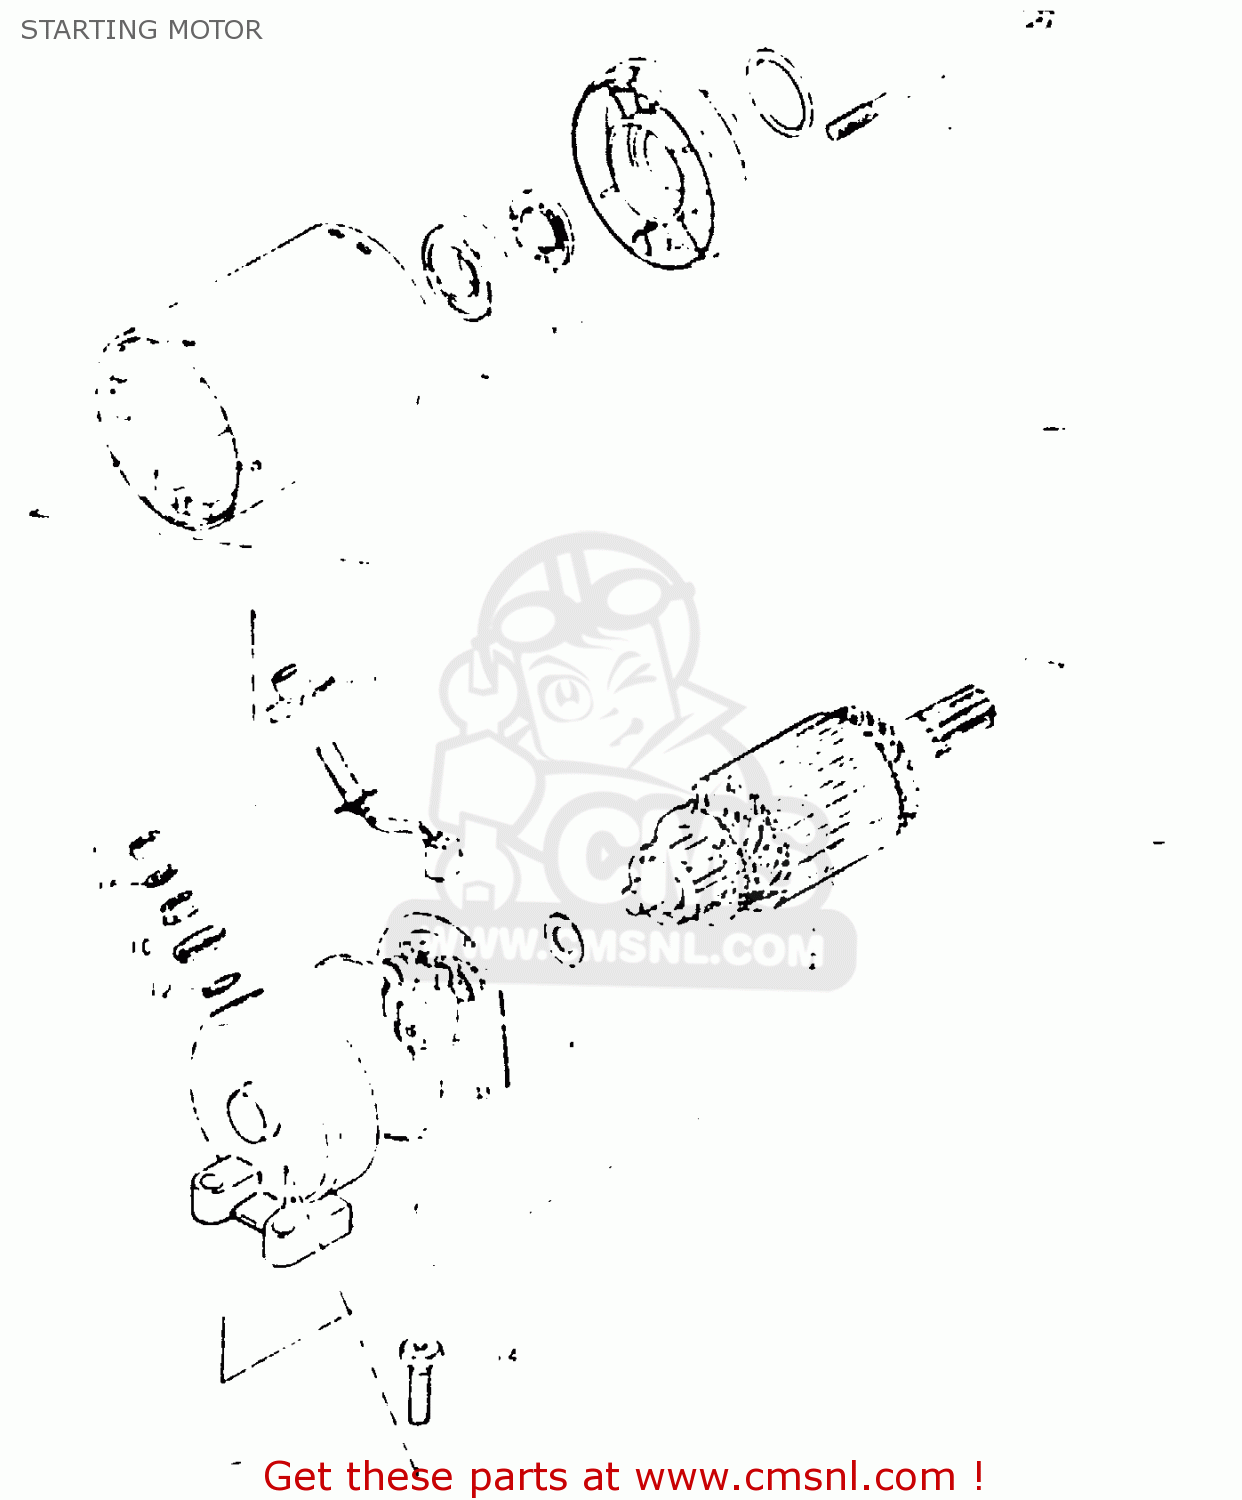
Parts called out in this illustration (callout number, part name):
1	MOTOR ASSEMBLY,STARTING
2	ARMATURE
3	SEAL,OIL
4	BEARING
5	SHIM,ARMATURE
6	O RING
7	HOLDER,BRUSH
8	SPRING
9	BRUSH (+)
10	BUSHING (1)
11	BUSH,NO.2
12	O-RING
13	BOLT,STARTING MOTOR HOUSING
14	SCREW (6X25)
15	NUT 6MM
16	LOCK WASHER
17	O RING(D:2,ID:24.5)
